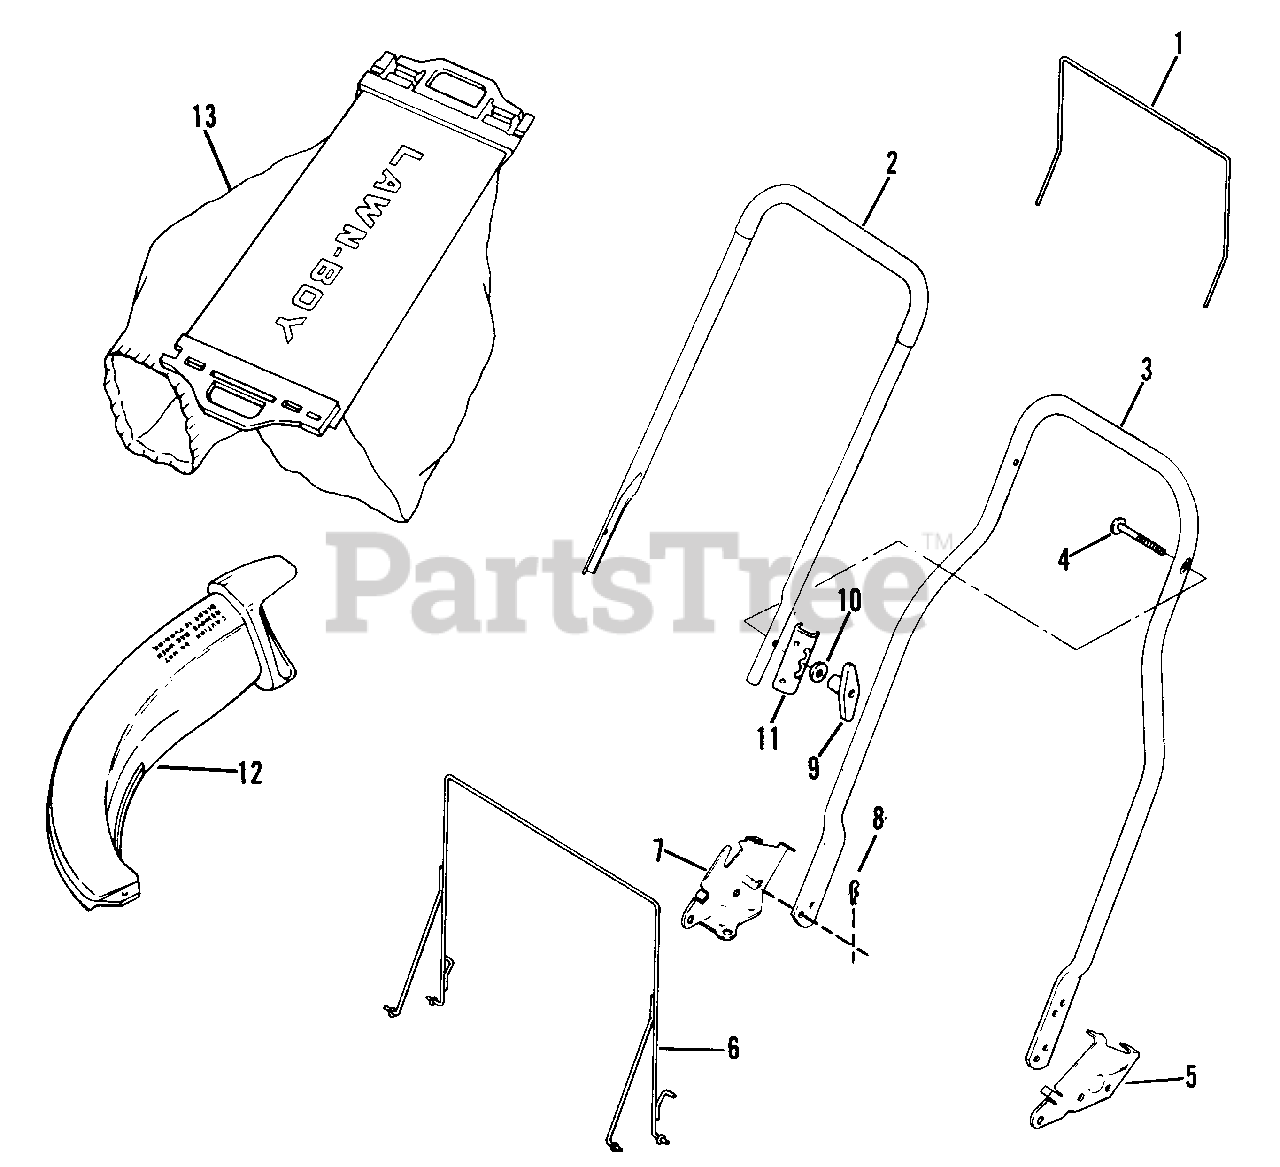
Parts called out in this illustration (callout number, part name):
1	Hanger-Rear
2	Top Handle & Grip Assembly
3	Handle Section-Bottom
4	Screw
5	Handle Bracket-L.H.
6	Hanger Assembly-Front
7	Handle Bracket-R.H.
8	Hair Pin
9	Knob
10	Washer-Curved
11	Bracket-Rear Hanger
12	Chute Assembly
13	Bag & Support Assembly
